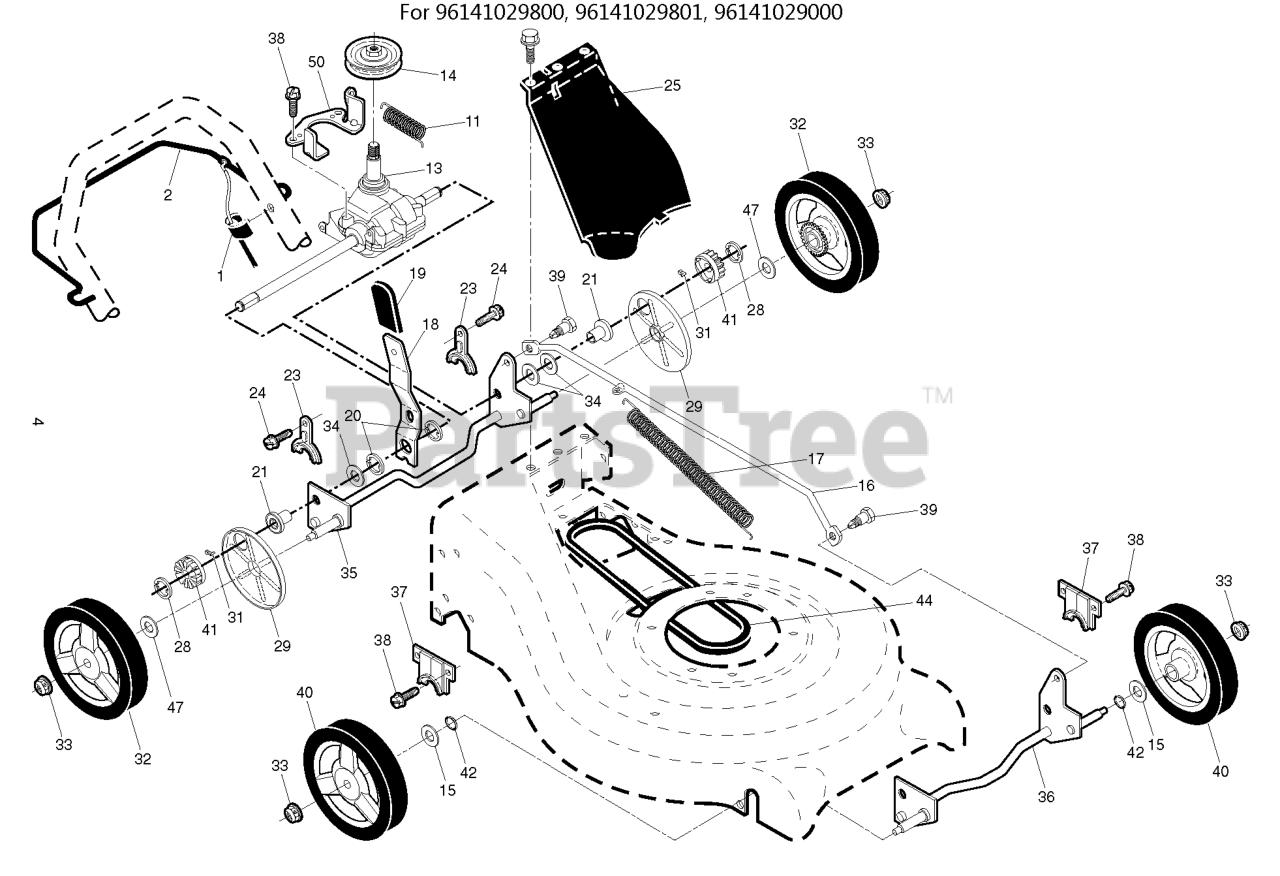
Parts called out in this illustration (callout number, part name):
1	CABLE.DR.21.RWGD.S.SPEED.MCCL
2	BAIL.CURVED.UNDER.BAIL.BLACK
13	TRANSMISSION.21.RWGD
14	PULLEY.RGD.SS.3.25OP
15	WASHER.FLAT.1/2
16	ROD.CONNECTING.SPT.BLACK
17	SPRING EXTENSION
18	SPRING.SELECTOR.
19	KNOB.EXT.ERGO.BLACK
21	BEARING.ASM.RGD.AUTO.SP
23	BRACKET
24	SCREW 14-20 X 5/8
25	COVER.DR.ASM.199775X418.CE
28	E-RING 7/16 RE
29	COVER.DUST.WHEEL.INNER.WALK
31	PAWL, DRIVE
32	WHEEL.8X1.75.3SPK.RAD3.GREY
33	NUT.HEX.FLANGE.3/8-16.LO(3 2)
35	SHAFT ASSY REAR
36	SHAFT ASSY, FRONT
37	RETAINER.FRONT.SHAFT
39	SHOULDER BOLT SEMI GIMLET PT.
40	WHEEL & TIRES ASSY, FRONT
41	PINIION.14.TOOTH.RGD
42	O-RING..070X.487.NEOPRENE
44	BELT.DRIVE.RWD+.SS.ZINC DUST
47	WASHER FLUT
50	BRACKET.BELT.KEEPE/AUT*SUBS/2*
